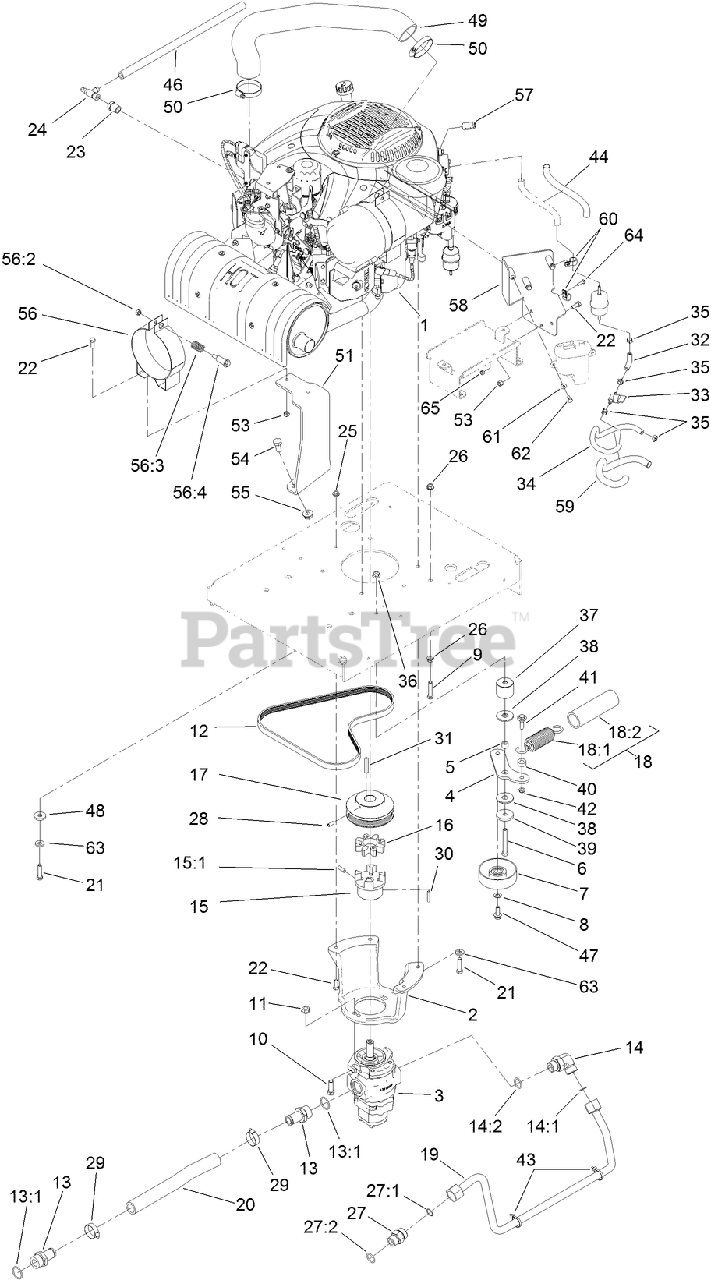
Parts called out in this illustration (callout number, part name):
1	ENGINE-KOHLER
2	MOUNT-PUMP [PRIMED]
3	GEAR PUMP ASM
4	ARM-IDLER
5	BUSHING-LEVER, LIFT
6	SCREW-HH
7	PULLEY-IDLER
8	WASHER-FLAT
9	SCREW-HH
10	SCREW-HH
11	NUT-HF
12	BELT-V
13	FITTING-STR
13:1	O-RING
14	FITTING-ELBOW-90
14:1	O-RING
14:2	O-RING
15:1	SCREW-SET
16	SPIDER
18	SPRING AND RETAINER KIT
18:1	SPRING-EXTENSION
18:2	RETAINER-SPRING
19	TUBE-HYD
20	HOSE-SUCTION
21	SCREW-HH
22	SCREW-HH
23	BUSHING
24	VALVE-DRAIN, OIL
25	NUT-HF
26	NUT-HHF, WHIZ
27	FITTING-HYD, STRAIGHT
27:1	O-RING
27:2	O-RING
28	SCREW-SET, HSH
29	CLAMP-HOSE
30	KEY-SQUARE
31	KEY-SQUARE
32	HOSE-FUEL
33	VALVE-FUEL
34	HOSE-FUEL
35	CLAMP-HOSE
36	NUT-HF, NI
37	SPACER-IDLER
38	WASHER-FRICTION, COMPOSITE
39	WASHER-PLAIN
40	SPACER
41	SCREW-SHOULDER, HWH
43	TIE-CABLE
44	SLEEVE-THERMAL
47	SCREW-HHF
48	WASHER
49	HOSE-INTAKE, AIR
50	CLAMP-HOSE
51	PLATE-MOUNT, FILTER
53	NUT-LOCK, NI
54	SCREW-HH
55	NUT-HHF
56	BAND-MOUNTING, AIR CLEANER
56:3	SPRING
56:4	NUT
57	FERRITE-SNAP ON
58	BRACKET-PUMP, FUEL
59	SLEEVE-THERMAL
60	CLAMP-CABLE
61	WASHER-FLAT
62	SCREW-HH
63	WASHER-BELLEVILLE
64	SCREW-HH
65	NUT-LOCK, NI
